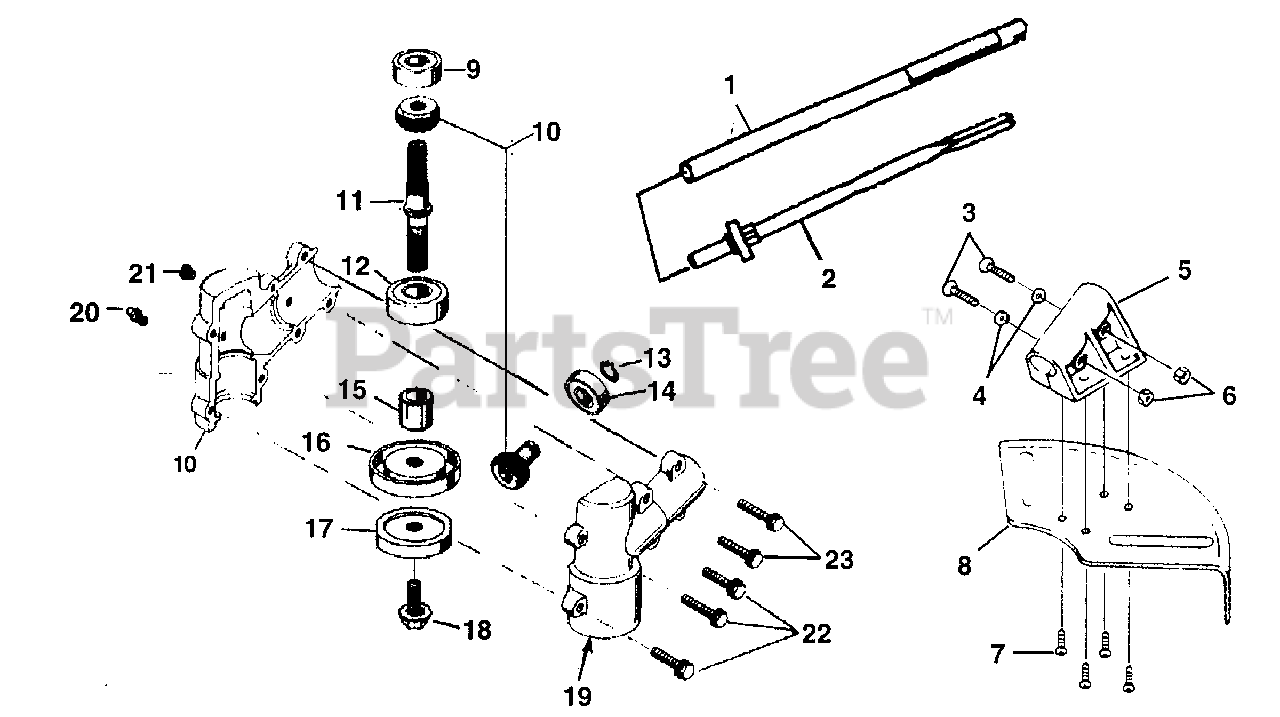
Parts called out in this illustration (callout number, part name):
1	TUBE ASSY.
2	FLEX CABLE
3	SCREW
7	SCREW, SELF TAPPING
8	GUARD
9	BEARING
11	SHAFT, GEAR
12	BEARING
14	BEARING
16	UPPER FLANGE WASHER
17	LOWER FLANGE WASHER
18	SEMS SCREW, BLADE
19	HOUSING SET
20	FITTING, ZERK
21	SCREW, SELF TAPPING
22	SCREW, SELF TAPPING
23	SCREW, SELF TAPPING
